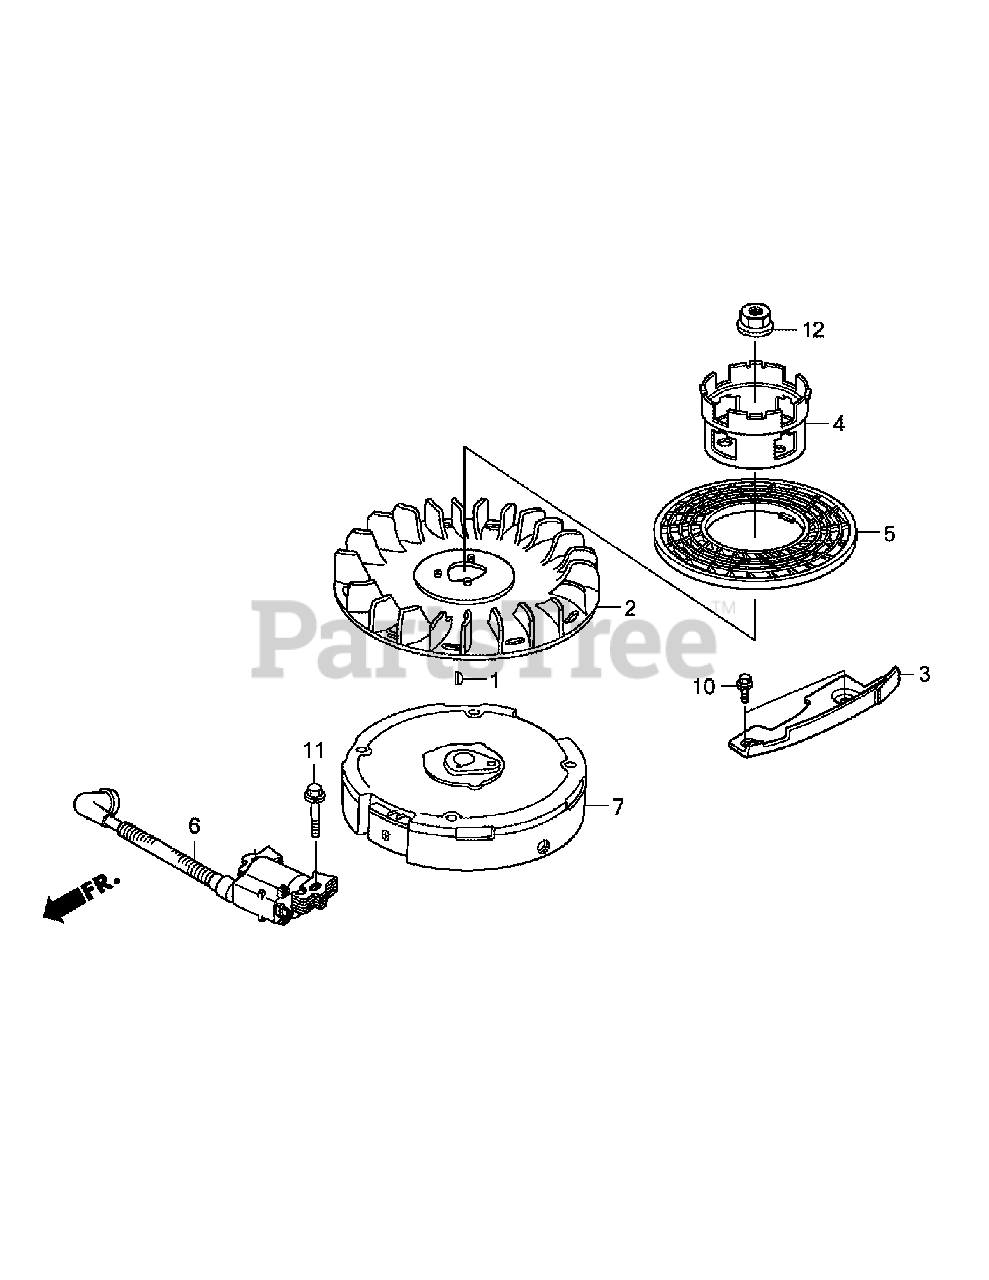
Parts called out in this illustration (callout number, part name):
1	Woodruff Key
2	Cooling Fan
3	Side Plate
4	Starter Pulley
6	Ignition Coil Assembly
7	Flywheel
10	Flange Bolt, 6 x 12
11	Flange Bolt, 6 x 23
